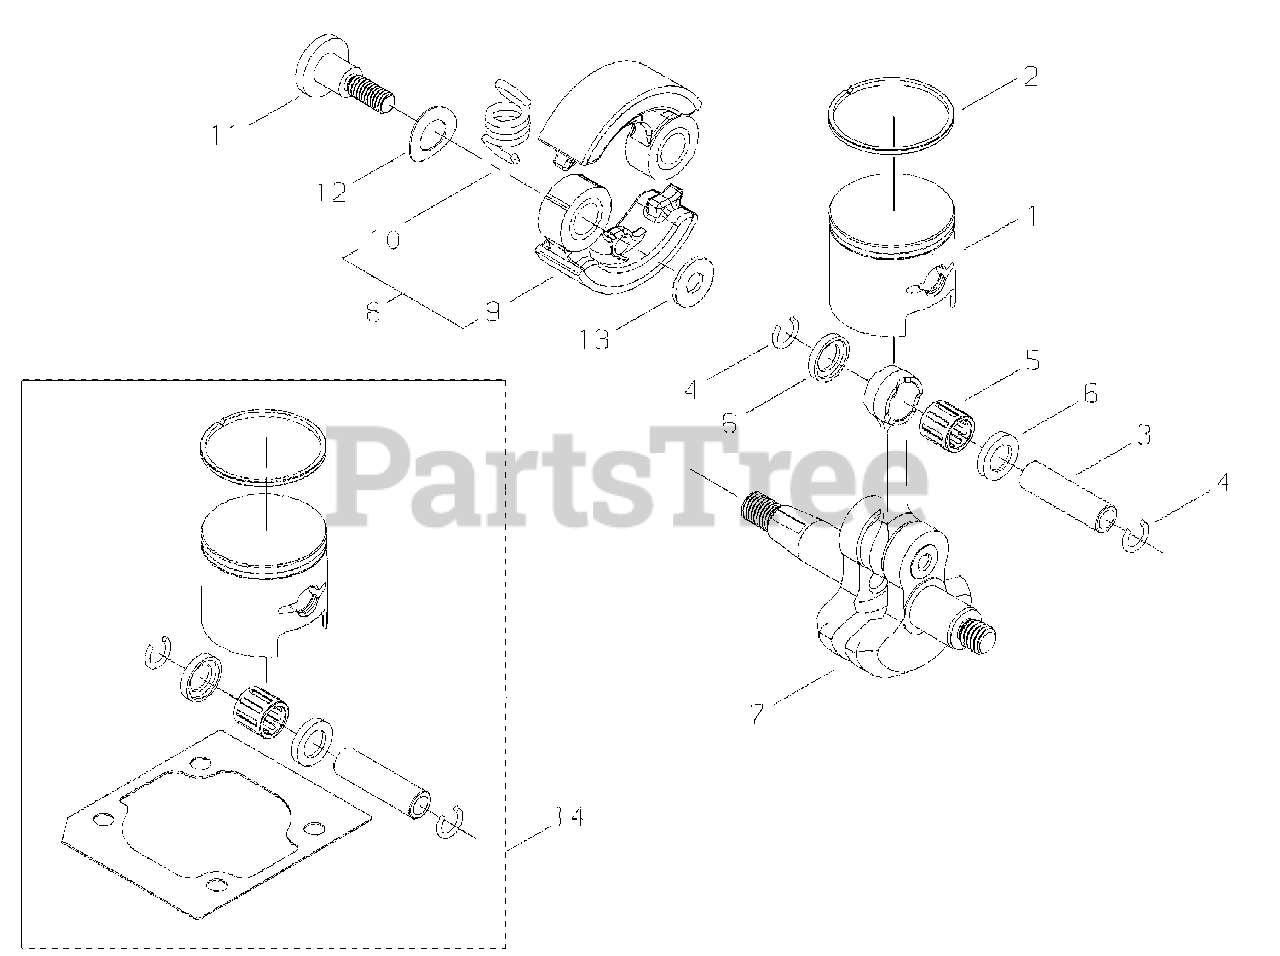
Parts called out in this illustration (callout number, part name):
1	PISTON
2	RING, PISTON
3	PIN, PISTON 8
4	RING, SNAP
5	BEARING, NEEDLE 8
6	WASHER, THRUST 8
7	CRANKSHAFT ASSY
8	CLUTCH KIT
9	SHOE, CLUTCH
10	SPRING, CLUTCH
11	BOLT
12	WASHER, SPRING
13	WASHER 6 MM
14	PISTON KIT
